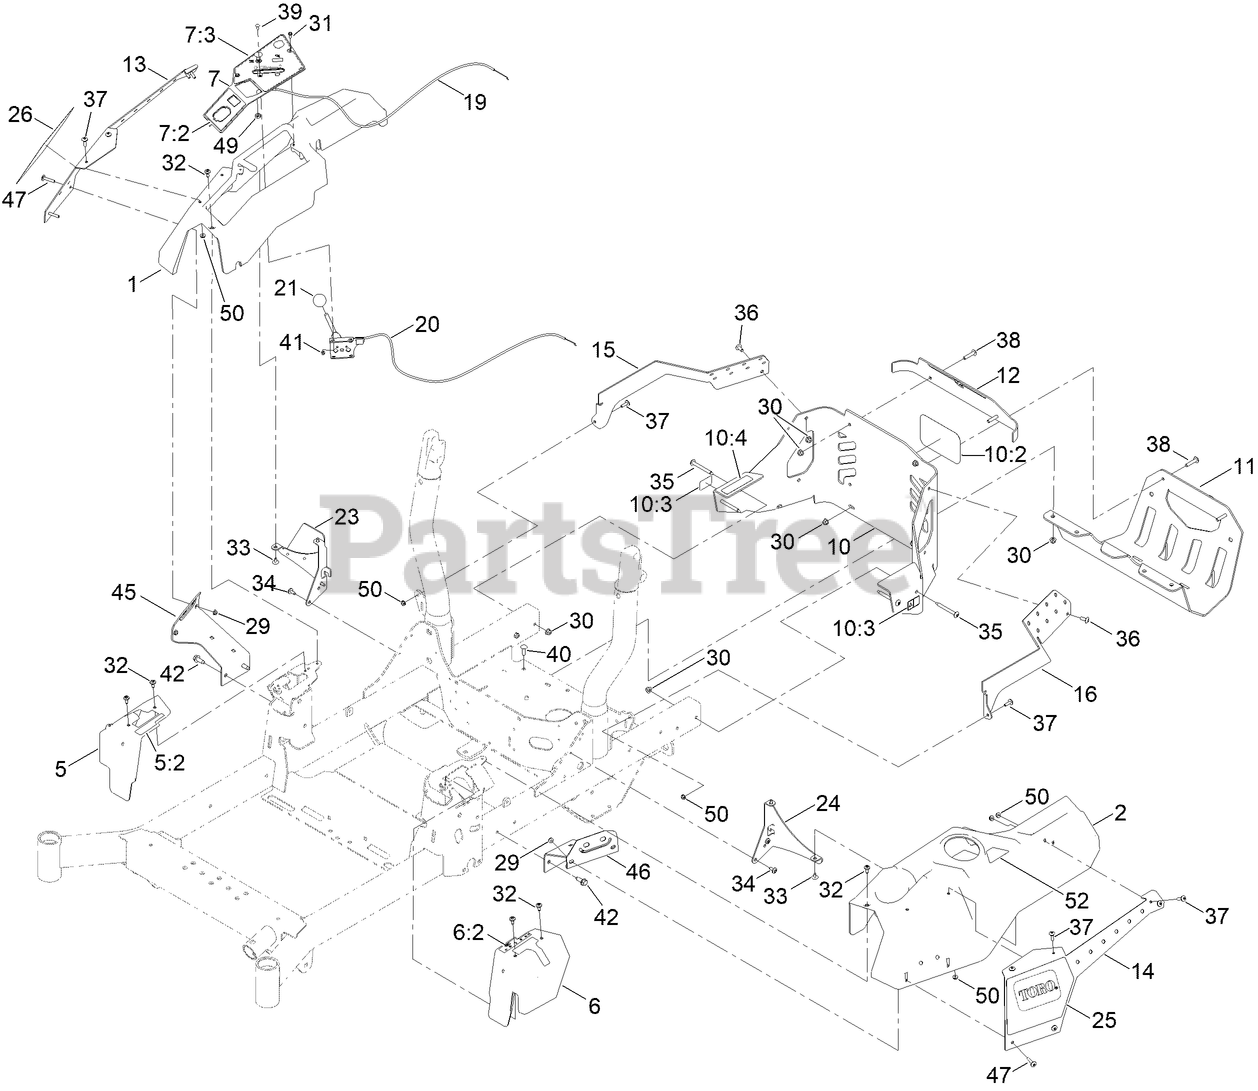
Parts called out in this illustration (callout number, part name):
1	CONSOLE-RH
2	CONSOLE-LH
5	COVER-CONTROL, MOTION (RH)
5:2	DECAL-CONTROL, MOTION (RH)
6	COVER-CONTROL, MOTION (LH)
6:2	DECAL-CONTROL, MOTION (LH)
7	CONTROL PANEL ASM
7:2	DECAL-PANEL, CONTROL
7:3	DECAL-PANEL, CONTROL
10	REAR GUARD ASM
10:2	DECAL
10:3	DECAL-WARNING
10:4	DECAL-ARRESTOR, SPARK
11	GUARD-MUFFLER
12	TRIM-UPPER REAR
13	COVER,POD RH
14	COVER [BLACK]
15	BRACKET-GUARD, RH
16	BRACKET-GUARD, LH
19	CABLE-CONTROL, CHOKE
20	CABLE-CONTROL, THROTTLE
21	KNOB-BALL
23	SUPPORT-CONSOLE, RH
24	BRACKET-CONSOLE, LH
25	DECAL - HDX
26	DECAL - HDX
29	NUT-HF
30	NUT-HF, NI
31	SCREW-HWH
32	SCREW-SHOULDER
33	SCREW-TORX
34	SCREW-TORX
35	SCREW-TORX
36	SCREW-TORX
37	SCREW-TRUSS
38	SCREW-TORX
39	BOLT-CARR
40	SCREW-CARR
41	NUT-LOCK, NI
42	SCREW-FORMING, THREAD
45	BRACKET-SUPPORT, POD (RH)
46	BRACKET-SUPPORT, POD (LH)
47	SCREW-TRUSS
49	NUT-HJ
50	NUT-KEPS
52	DECAL-FILL, FUEL
